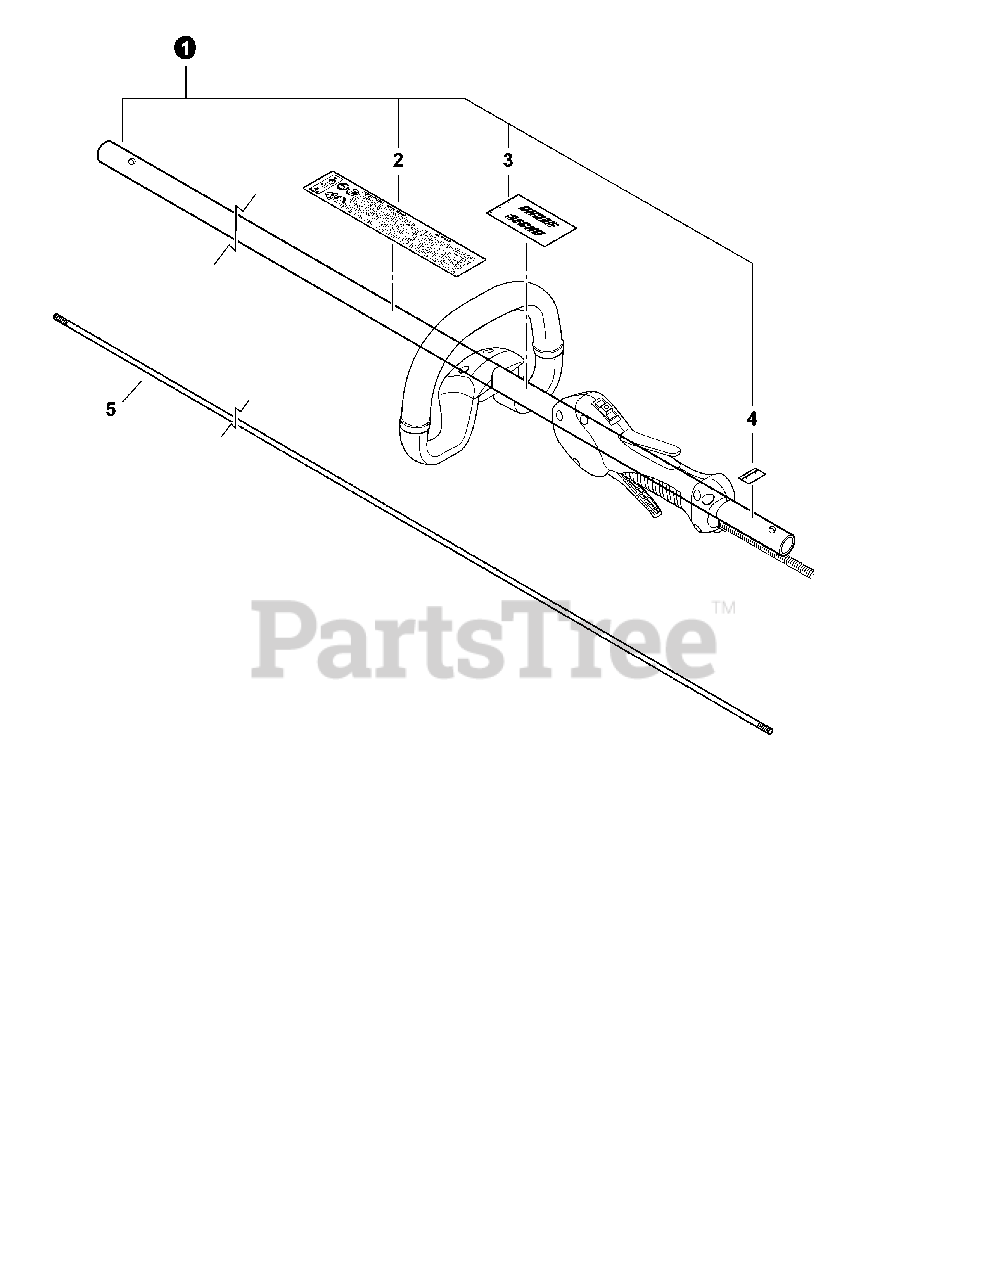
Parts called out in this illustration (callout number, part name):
1	MAIN PIPE ASY
2	LABEL - CAUTION
3	LABEL - HANDLE LOCATION
4	LABEL - ALIGNMENT
5	DRIVESHAFT - SOLID
